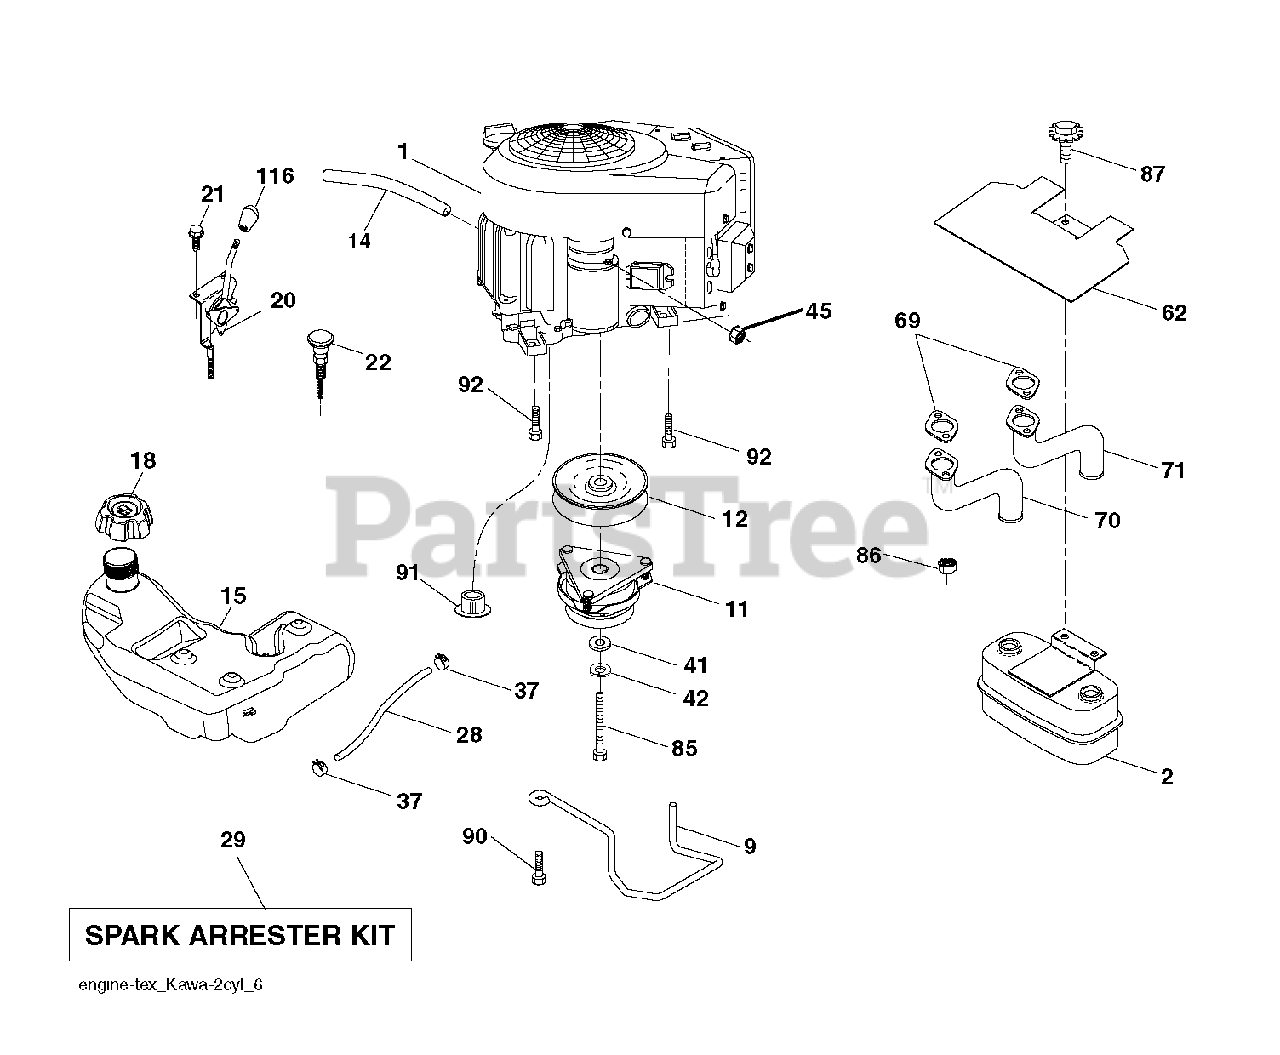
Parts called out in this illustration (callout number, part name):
2	MUFFLER.TWIN.CYL.LOW.TONE
12	PULLEY ENGINE
14	TUBE, DRAIN OIL ASM.
15	TANK.FUEL.4GAL
18	CAP.ASM.FUEL.TANK.3"BLACK
20	CONTROL.THROTTLE.PRO.
21	SCREW.#10 X 0.750.BOS THREAD
22	CONTROL CHOKE
29	ARRESTER SPARK (OPTIONAL)
37	HOSE CLAMP
42	LOCKWASHER
62	SHIELD.HEAT.MUFFLER
70	TUBE.EXHAUST
71	TUBE.EXHAUST
85	BOLT HEX 7/16-20 X 3.75 GR. 5
86	NUT.HEX.FLANGE.TOPLOCK
87	BOLT.5/16-18UNCX1.W/SEMS.BLK
90	SCREW 3/8-16X1
91	BUSHING.1.375OD
92	SCREW 3/8-16X1
